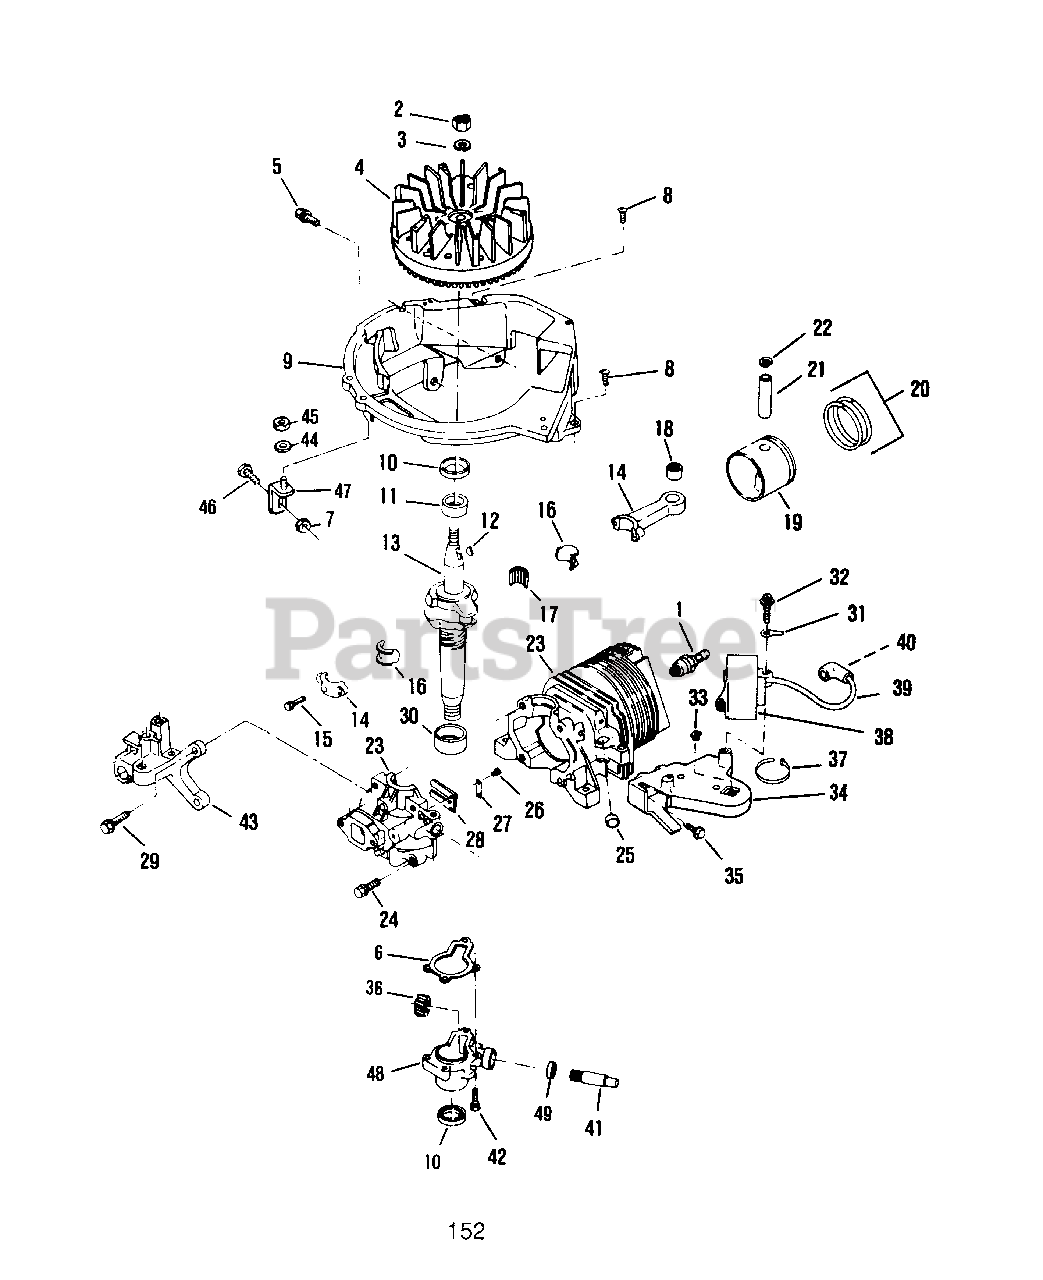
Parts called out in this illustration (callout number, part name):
1	Spark Plug
2	Nut-Flywheel
3	Lockwasher
4	Flywheel
5	Screw
6	Gasket-Gear Box
7	Nut
8	Screw-Shroud Base to C.D. Brkt. and Clamp to Shroud Base
9	Base-Shroud
10	Oil Seal
11	Bearing-Upper
12	Key-Flywheel
13	Crankshaft
14	Connecting Rod Assembly
15	Screw-Cap
16	Liner-Split
17	Needle Bearing Set
18	Bearing Assembly
19	Piston and Ring Set
20	Ring Set
21	Wrist Pin
22	Retaining Ring
23	Cylinder and Crankcase Cover Assembly
24	Screw-Cover to Crankcase
25	Plug
26	Screw-Reed to Crankcase Cover
27	Plate-Reed Hold Down
28	Reed
29	Screw-Brake Mounting Brkt.
30	Bearing-Lower
31	Terminal-Ground Lead
32	Screw-C.D. Mounting
33	Grommet-C.D. Bracket
34	Bracket-Ignition Mounting
35	Screw
36	Gear
37	Tie Strap
38	C.D. Ignition Module and Lead Assembly
39	High Tension Lead and Cover Assembly
40	Spring Terminal
41	Driveshaft
42	Screw-Gear Box
43	Bracket-Brake
44	Washer
45	Nut
46	Bolt
47	Shroud Brace Assembly
48	Gear Box Assembly
49	Seal-Driveshaft
